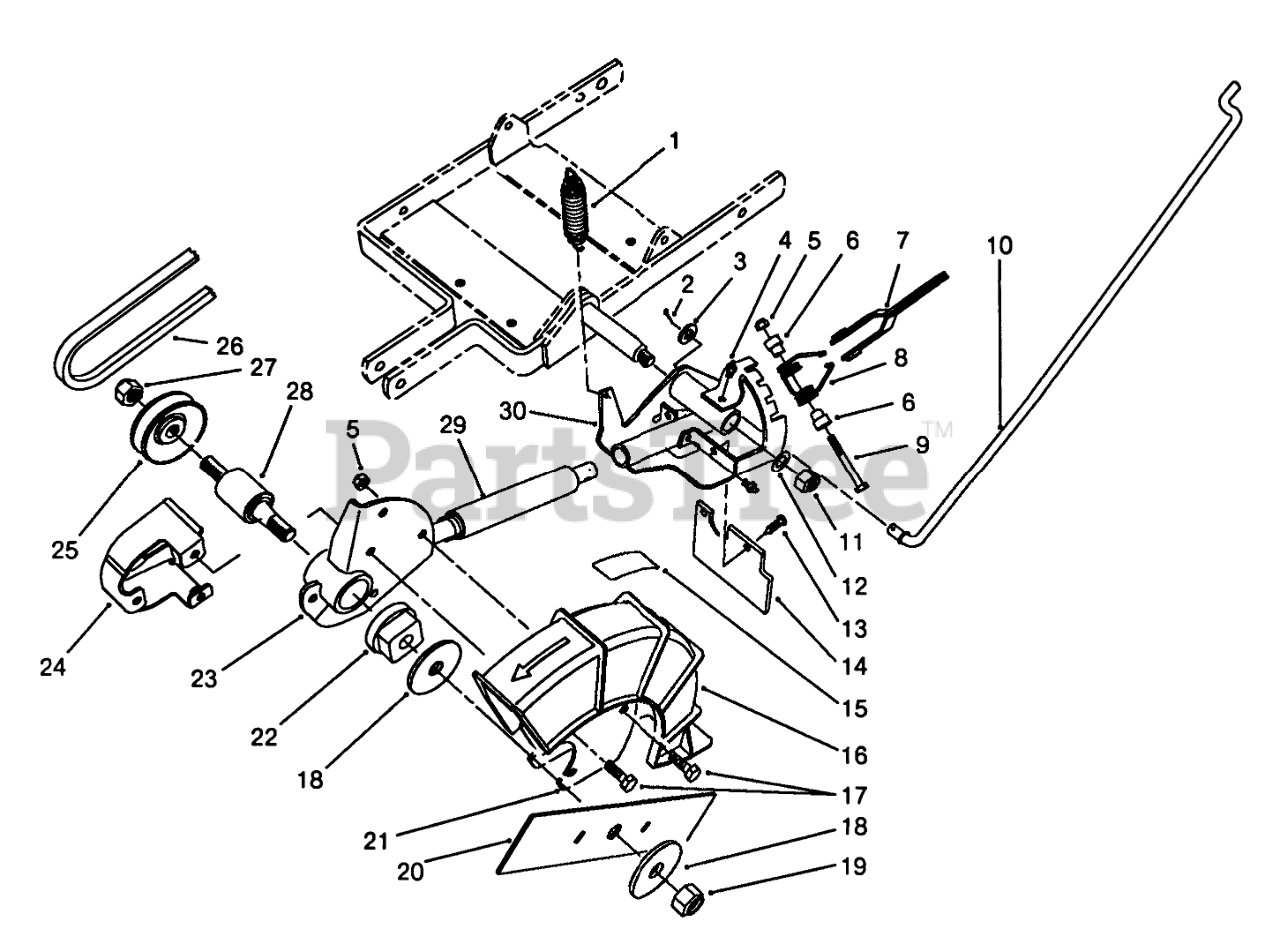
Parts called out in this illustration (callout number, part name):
1	EXT. SPRING
2	PIN-COTTER
3	WASHER-FLAT
4	FITTING-GREASE
5	NUT-LOCK, NI
6	SPACER-PIVOT LEVER
7	LEVER WA
8	TORSION SPRING
9	SCREW-HH
10	LOWER CONTROL ROD
11	NUT-LOCK, NI
12	WASHER-PLAIN
13	216 Washer
14	RUBBER GUARD
15	Decal-Warning
16	Blade Guard Assembly (Incl. Ref. #15)
17	SCREW-HWHTF
18	WASHER-LARGE
19	NUT-HEX
20	10" EDGER BLADE B
21	GUARD PLATE
22	BRG SHIELD
23	HUB ASM
24	PULLEY GUARD WA
25	PULLEY
26	V-BELT
27	NUT-LOCK, NI
28	SPINDLE ASM
29	SPRING & BELLOW ASM
30	PIVOT ARM WELDMENT B
